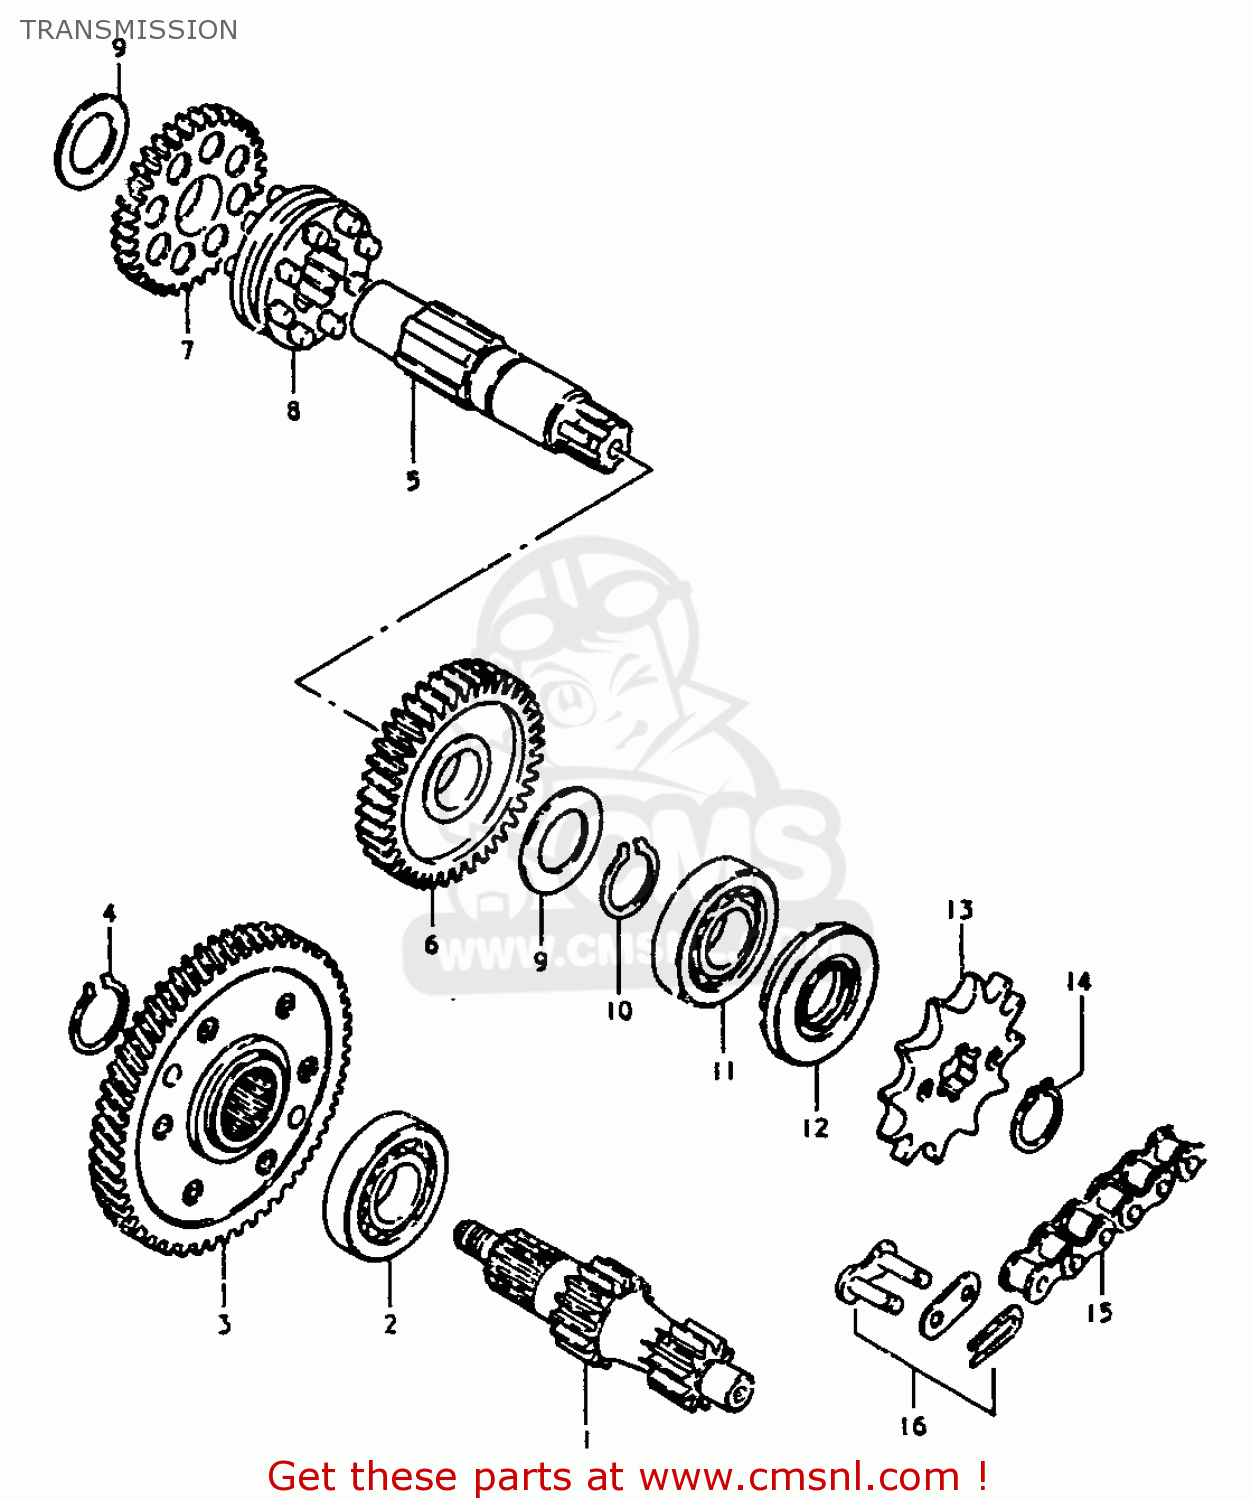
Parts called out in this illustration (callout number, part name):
1	SHAFT,COUNTER
2	BEARING(17X40X12)
3	GEAR ASSEMBLY,PRIMARY DRIVE
4	CIRCLIP
5	SHAFT,DRIVE
6	GEAR,FIRST DRIVEN
7	GEAR,SECOND DRIVEN
8	WHEEL,1ST GEAR
9	WASHER,THRUST
10	CIRCLIP
11	BEARING(17X40X12)
12	SEAL,OIL(17X29X7)
13	SPROCKET,ENGINE
14	CIRCLIP,16MM
15	CHAIN ASSEMBLY,DRIVE
16	JOINT
